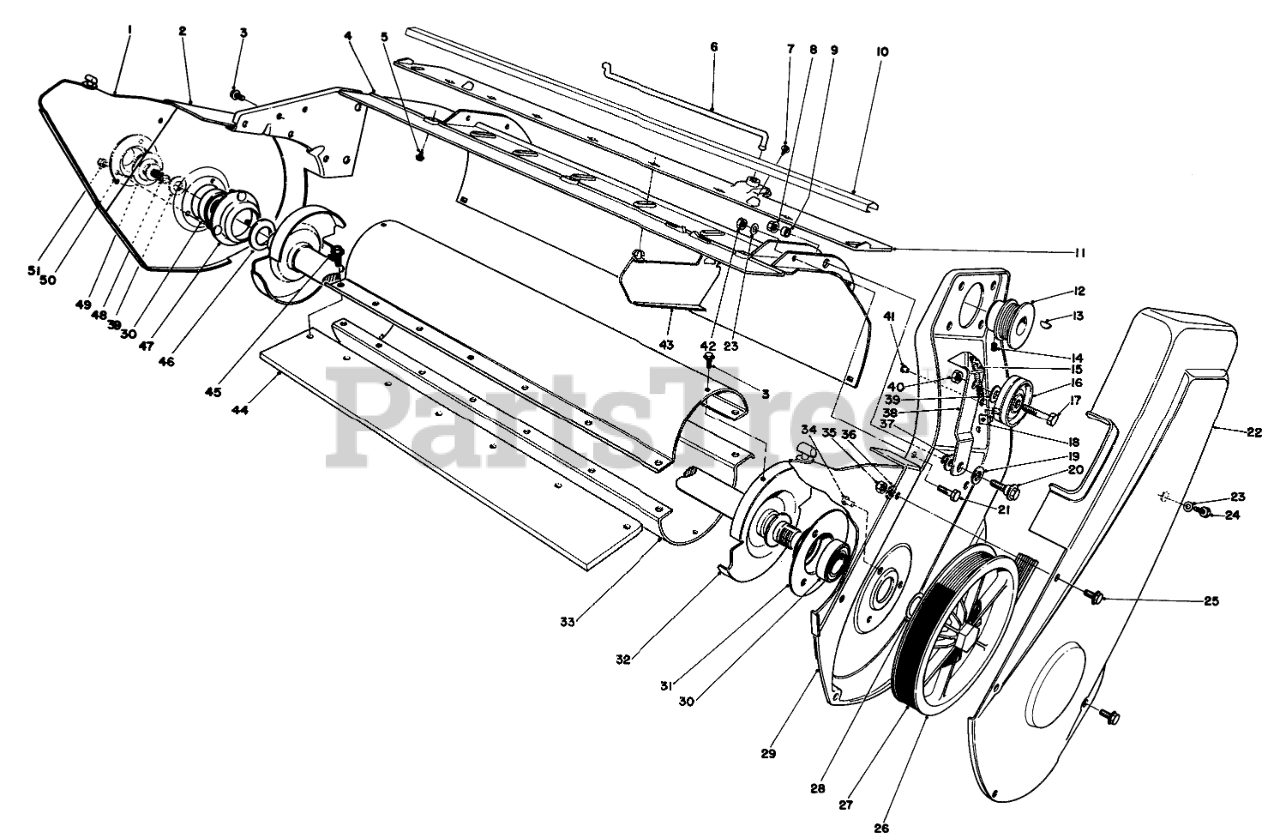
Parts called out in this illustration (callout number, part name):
1	OUTSIDE VANE
2	Plate-R.H. Side
3	SCREW
4	HOUSING ASSEMBLY
5	SCREW-HWHTF
6	VANE ADJ LINKAGE
7	10-16 X 3/8 THDG SCREW
8	NUT-HF
9	SPACER
10	Molding
11	Mount-Vane
12	Pulley
13	KEY-WOODRUFF
14	SCREW-HSH
15	IDLER SPRING
16	IDLER PULLEY
17	SCREW-HH
18	TINNERMAN NUT
19	WASHER
20	SCREW-SHOULDER
21	SCREW-HH
22	Drive Cover
23	WASHER-FLAT
24	SCREW-HEX HD
25	SCREW-SHWH
26	PULLEY ASM ROTOR
27	BELT - DRIVE
28	WASHER
29	Plate-L.H. Side
30	BEARING-BALL
31	FLANGE-BEARING
32	END CAP WA
33	Shell-Rotor
34	RIVET
35	NUT-LOCK, NI
36	WASHER-FLAT
37	WASHER-PIVOT
38	IDLER ARM
39	WASHER-FLAT
40	NUT-LOCK, NI
41	Eyelet
42	NUT-LOCK, CONE
43	CENTER VANE
44	ROTOR BLADE
45	Screw
46	WASHER-THRUST
47	FLANGE-BEARING
48	SCREW-HHF
49	WASHER-RUBBER
50	Trough
51	NUT-CAP
